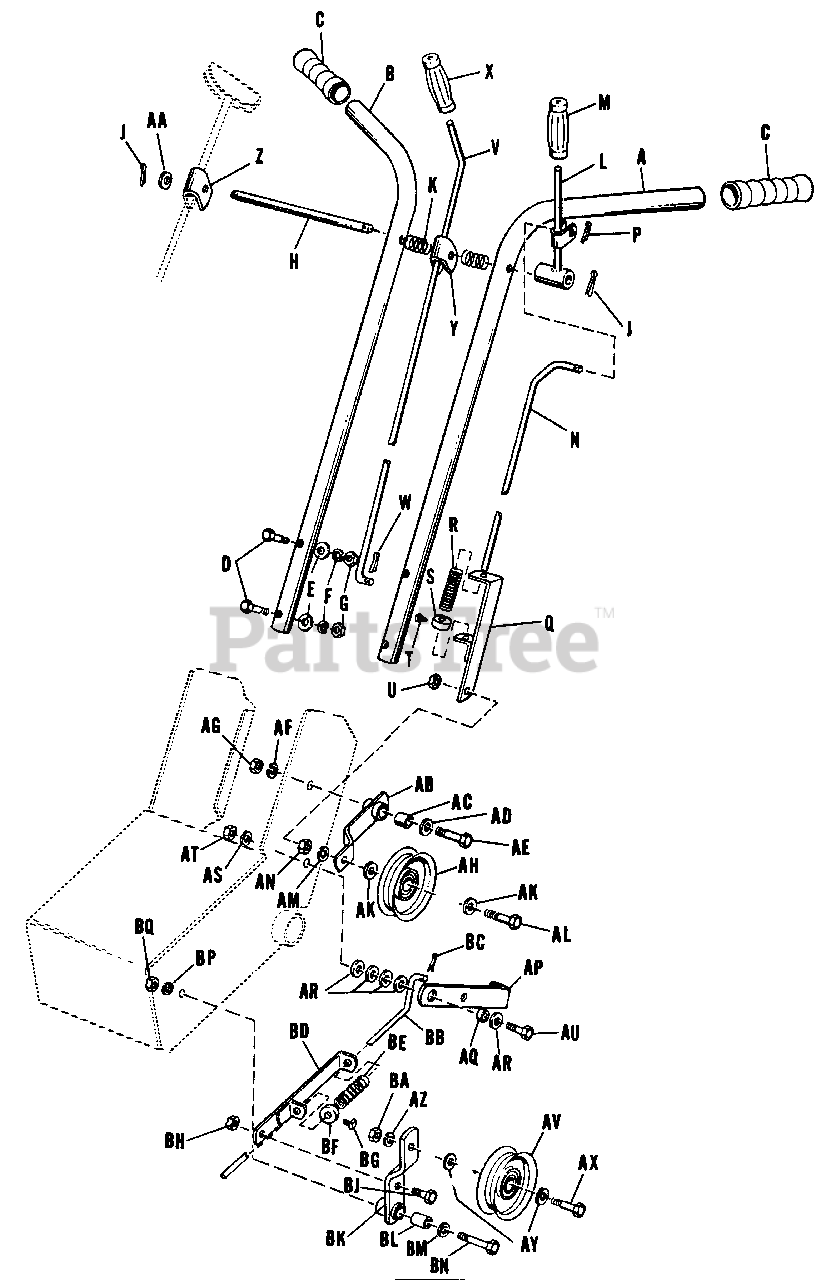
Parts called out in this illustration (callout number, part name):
A	Handle, Left Hand
B	Handle, Right Hand
C	Grip, Handle
D	CapScrew, Hex, 3/8"-16 NC x 1-3/4" lg.
E	Washer, Plain, 3/8"
F	Washer, Lock, 3/8"
G	Hex Nut, Full, 3/8"-16 NC
H	Pin, Lever
J	Pin, Cotter, 3/32" x 3/4" lg.
L	Lever Assembly, Left Hand
N	Rod, Clutch Transmission
P	Pin, Cotter, 3/32" x 3/4" lg.
Q	Guide Assembly, Rod
S	Collar, Set
T	Set Screw, Square Hd., 1/4"-20 NC x 3/8" lg.
U	Hex Nut, Full, Lock, 3/8"-16 NC
V	Rod, Reverse
W	Pin, Cotter, 3/32" x 3/4" lg.
Y	Guide, Reverse Rod
Z	Guide, Rod
AA	Washer, Plain, 5/16"
AB	Lever Assembly, Idler, (Transmission Clutch)
AC	Race, Inner Bearing
AD	Washer, Plain, 3/8"
AE	Capscrew, Hex, 3/8"-16 NC x 1-3/4" lg.
AF	Washer, Lock, 3/8"
AG	Hex Nut, Full, 3/8"-16 NC
AH	Pulley, Idler, (Transmission Drive)
AK	Washer, Plain, 3/8"
AL	Capscrew Hex, 3/8"-16 NC x 2" lg.
AM	Washer, Lock, 3/8"
AN	Nut, Hex, Full, 3/8"-16 NC
AP	Pedal, Clutch, Foot
AR	Washer, Plain, 3/8"
AS	Washer, Lock, 3/8"
AT	Nut, Hex, Full, 3/8"-16 NC
AU	Capscrew, Hex, 3/8"-16 NC x 1-1/2" lg.
AV	Pulley, Idler, (Rotor Drive)
AX	Capscrew, Hex, 3/8"-16 NC x 1-3/4" lg.
AY	Washer, Plain, 3/8"
AZ	Washer, Lock, 3/8"
BA	Nut, Hex, Full, 3/8"-16 NC
BB	Rod, Clutch, Rotor
BC	Pin, Cotter, 3/32" x 3/4" lg.
BD	Guide Assembly, Clutch Rod
BF	Collar, Set
BG	Set Screw, Square Hd., 1/4"-20 NC x 3/8" lg.
BH	Hex Nut, Full, Lock, 3/8"-16 NC
BJ	Capscrew, Hex, 3/8"-16 NC x 3/4" lg.
BK	Lever Assembly, Idler
BL	Race, Inner Bearing
BM	Washer, Plain, 3/8"
BN	Capscrew, Hex, 3/8"-16 NC x 1-3/4" lg.
BP	Washer, Lock, 3/8"
BQ	Nut, Hex, Full, 3/8"-16 NC
